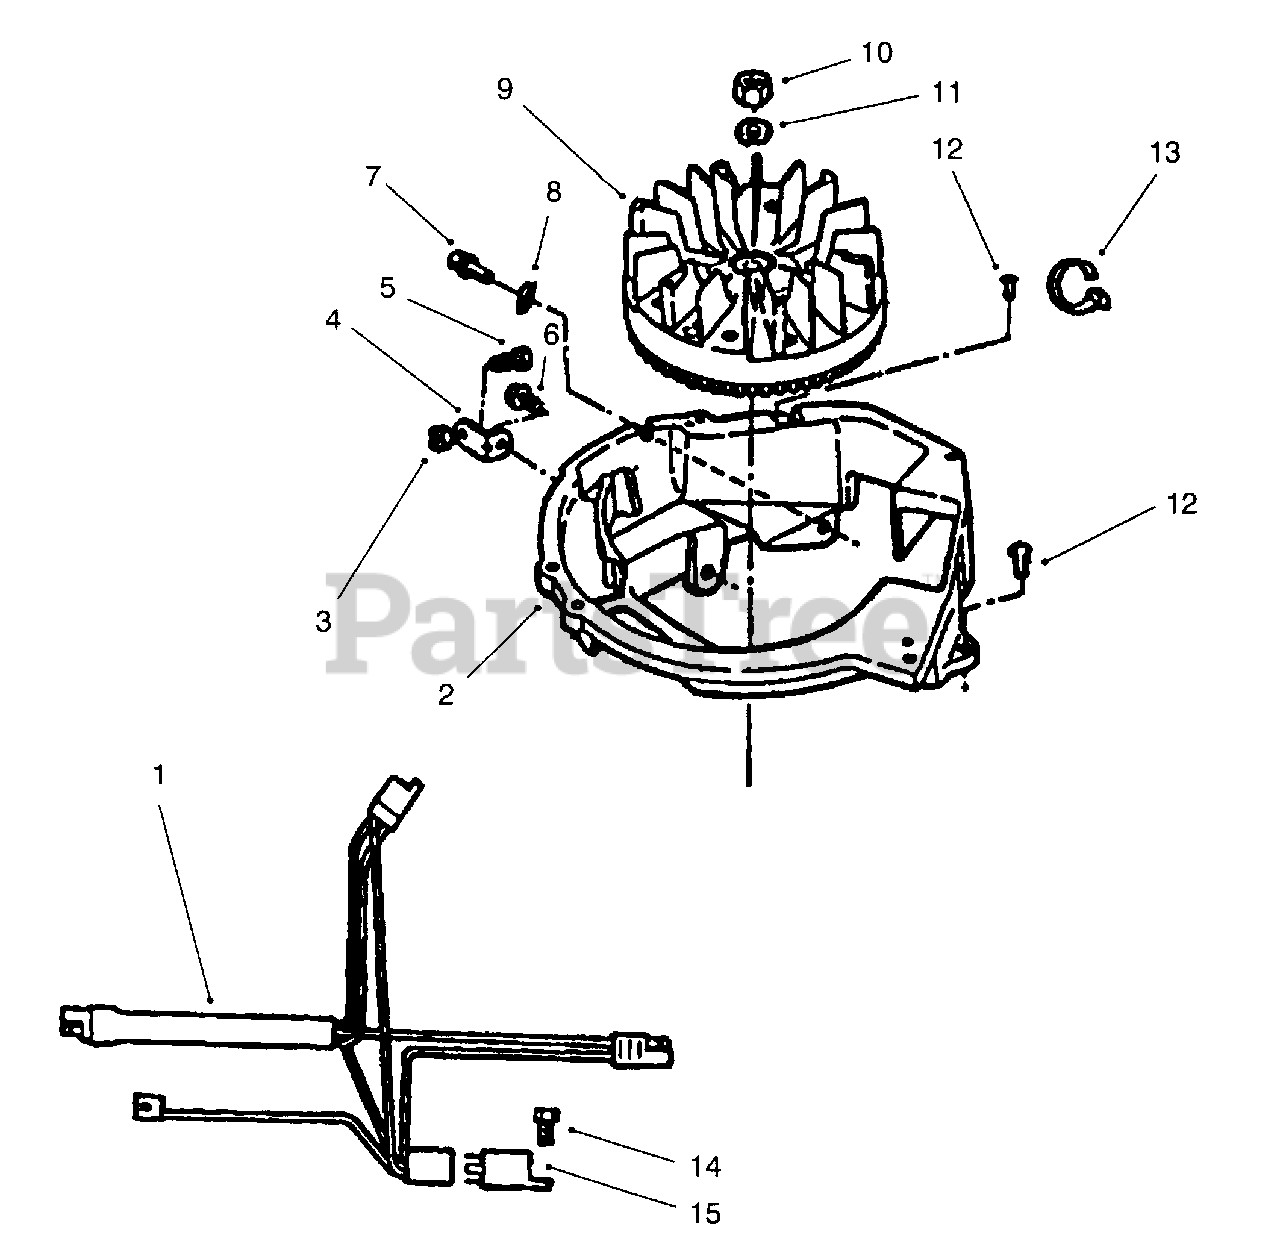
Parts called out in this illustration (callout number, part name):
1	Harness-Wire
2	Base-Shroud
4	Brace-Alternator
9	Flywheel
10	Nut-Flywheel
11	Washer-Lock
13	Strap-Tie
